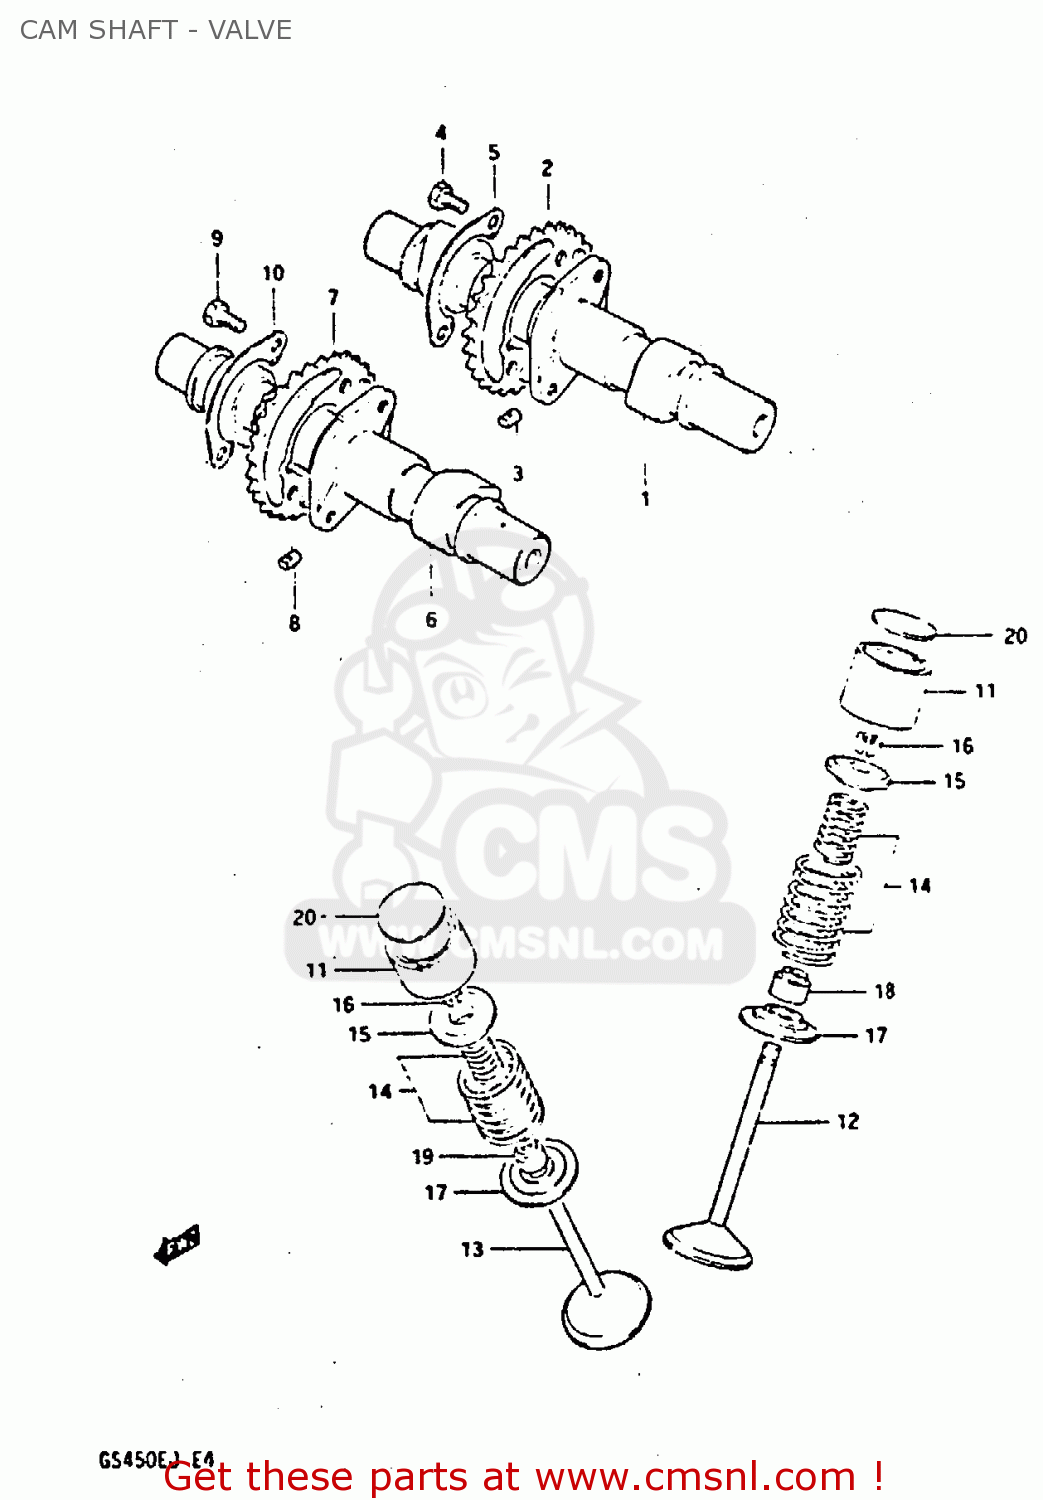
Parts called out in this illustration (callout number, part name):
1	CAMSHAFT,INTAKE
2	SPROCKET,CAMSHAFT
3	PIN,SPROCKET
4	BOLT(6X12.5)
5	WASHER,CAM CHAIN SPROCKET
6	CAMSHAFT,EXHAUST
7	SPROCKET,EXHAUST CAM(NT:30)
8	PIN,SPROCKET
9	BOLT(6X12.5)
10	WASHER,CAM CHAIN SPROCKET
11	TAPPET,INTAKE
12	VALVE,INTAKE
13	VALVE,EXHAUST
14	SPRING SET,VALVE
15	RETAINER,VALVE SPRING
16	COTTER VALVE
17	SEAT,VALVE SPRING
18	SEAL,OIL(7X14.4X9)
19	OIL SEAL, EXHAUST
20	SHIM,TAPPET(T:2.15)
